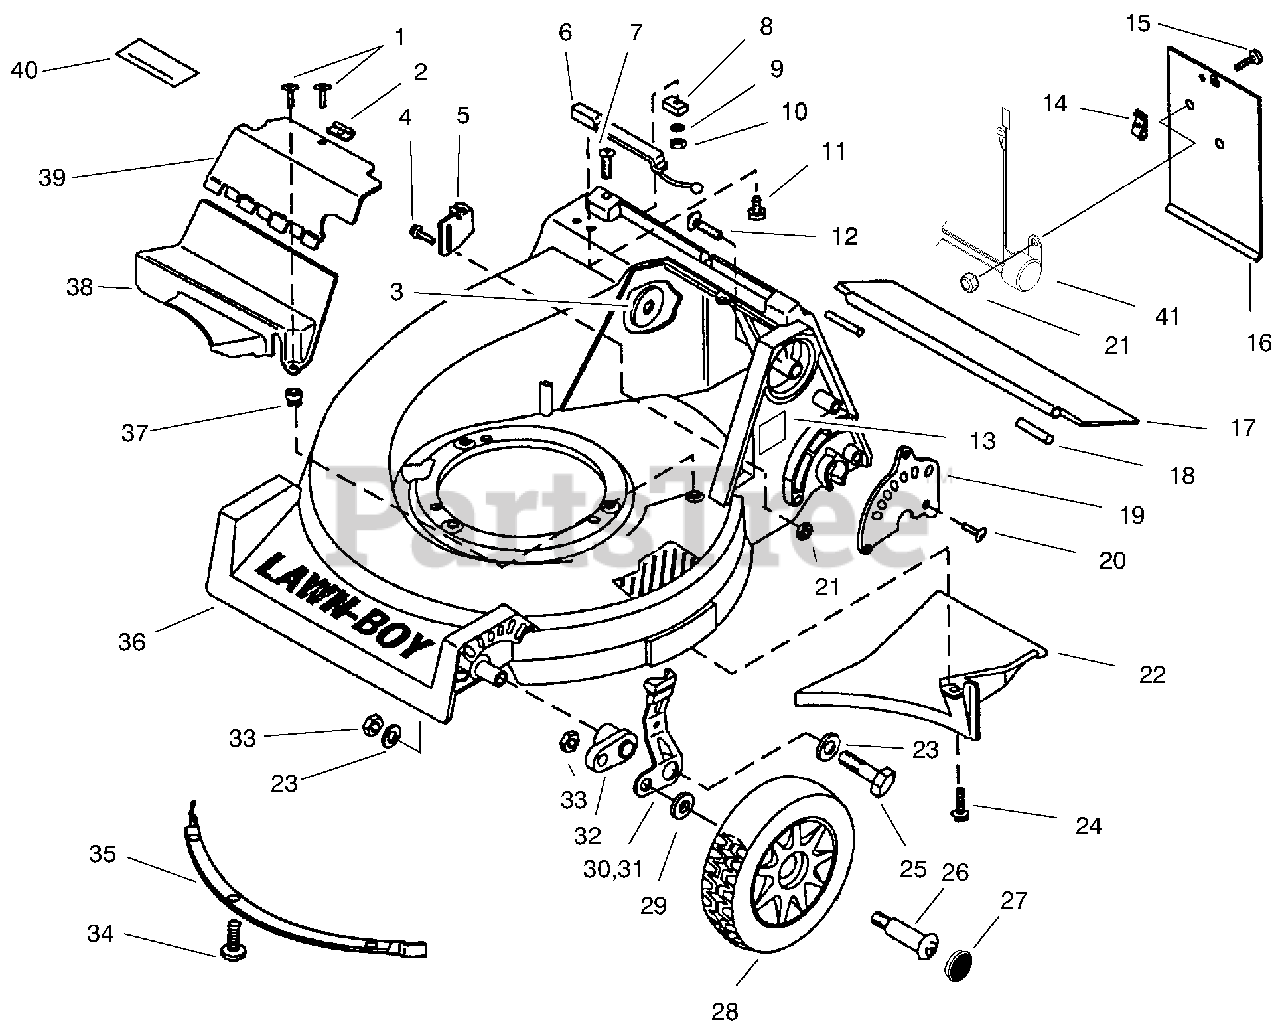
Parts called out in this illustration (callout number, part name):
2	Nut-Speed
3	Washer
5	Anchor-Cable
6	Switch Ass'y
9	Washer-Lock
11	Screw-Stainless
12	Bolt-Ribbed Neck
13	Decal-Noise
14	Nut-Speed
16	Door-Access
17	Shield-Trailing
20	Screw-Button Head
21	Nut-Lock
22	Baffle-Chute
24	Screw-Hex Washer Hd.
26	Bolt-Shoulder
28	Wheel & Tire Assembly 8"
30	Knob & Spring
31	Knob&Spring
32	Arm-Height Adjustment
33	Nut-Lock
34	Screw-Button Head
35	Baffle-Front
36	Housing-21" (Incl. Ref. #40 & 41)
37	Grommet
38	Cover-Drive Lower
39	Cover-Drive Upper
40	Decal-Danger
41	Harness-Bag Interlock
